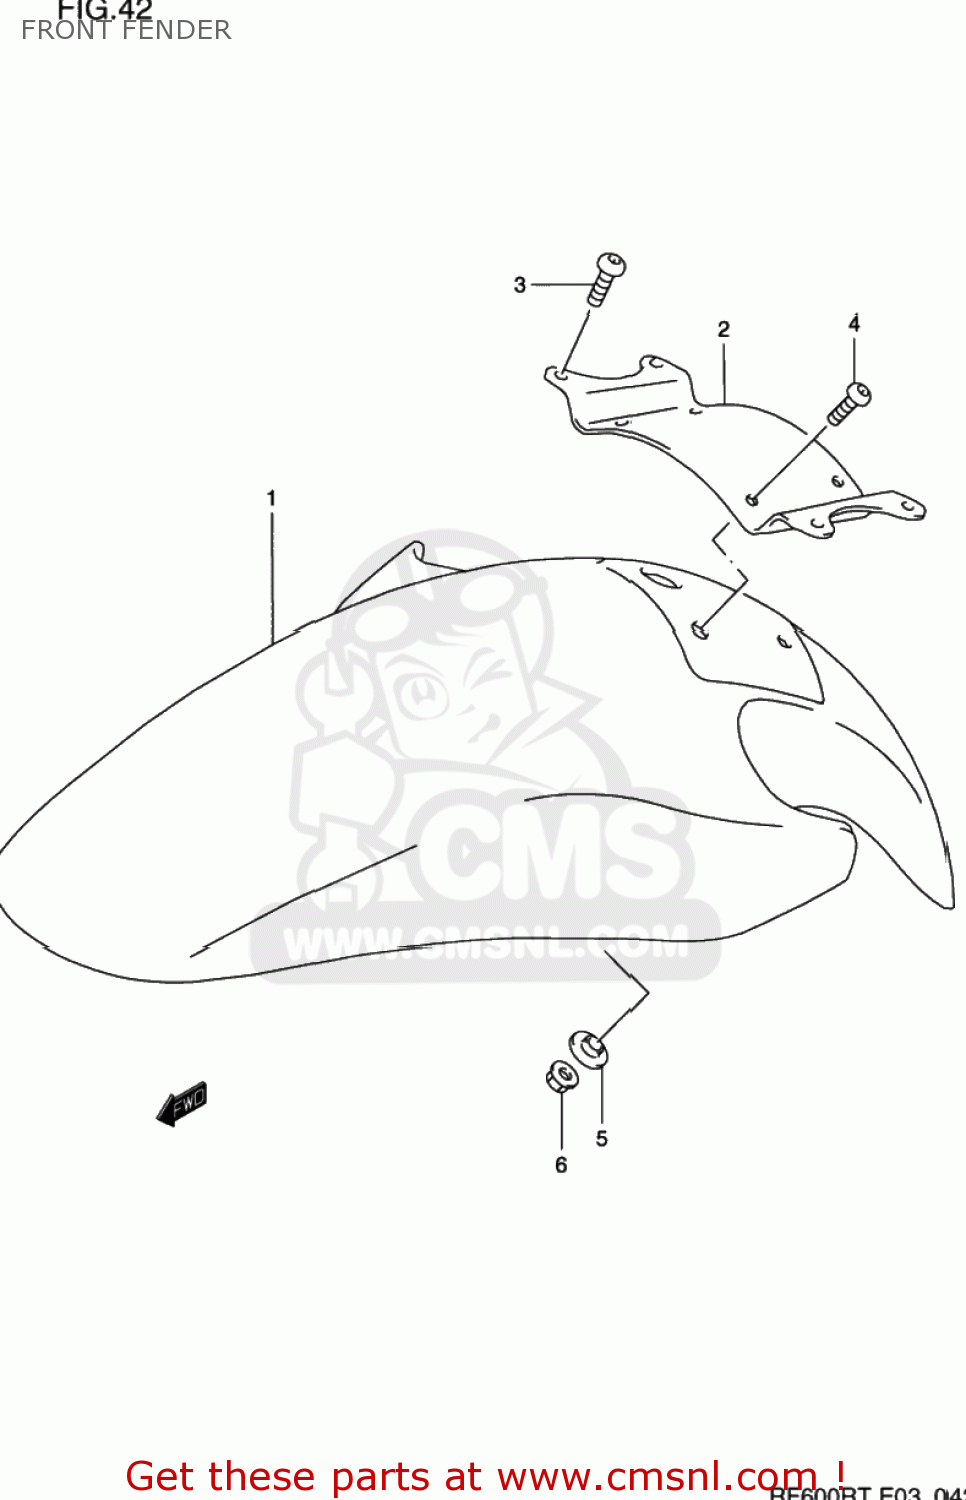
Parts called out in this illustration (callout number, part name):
1	FENDER SET,FR
2	BRACE,FR FENDER
3	SCREW(6X12)
4	SCREW(5X16)
5	WASHER
6	NUT
